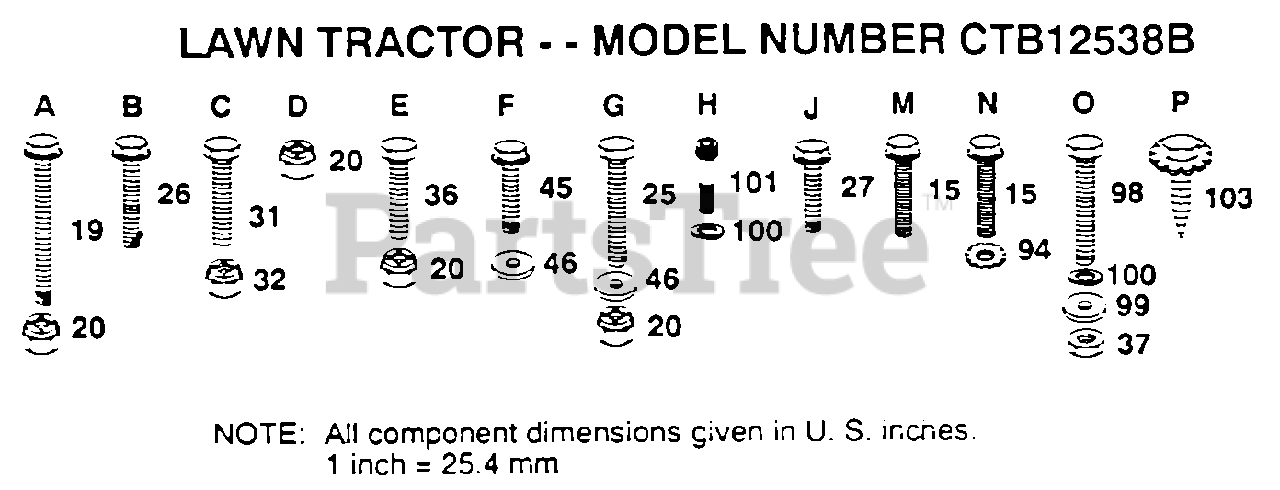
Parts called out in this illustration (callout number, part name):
15	SCREW
19	BOLT
25	BOLT
26	SCREW
27	SCREW LT
31	BOLT
37	NUT.HEX.5/16-18
45	SCREW
46	WASHER
94	LOCKWASHER
98	BOLT
99	WASHER
100	LOCKWASHER
101	SCREW LT
